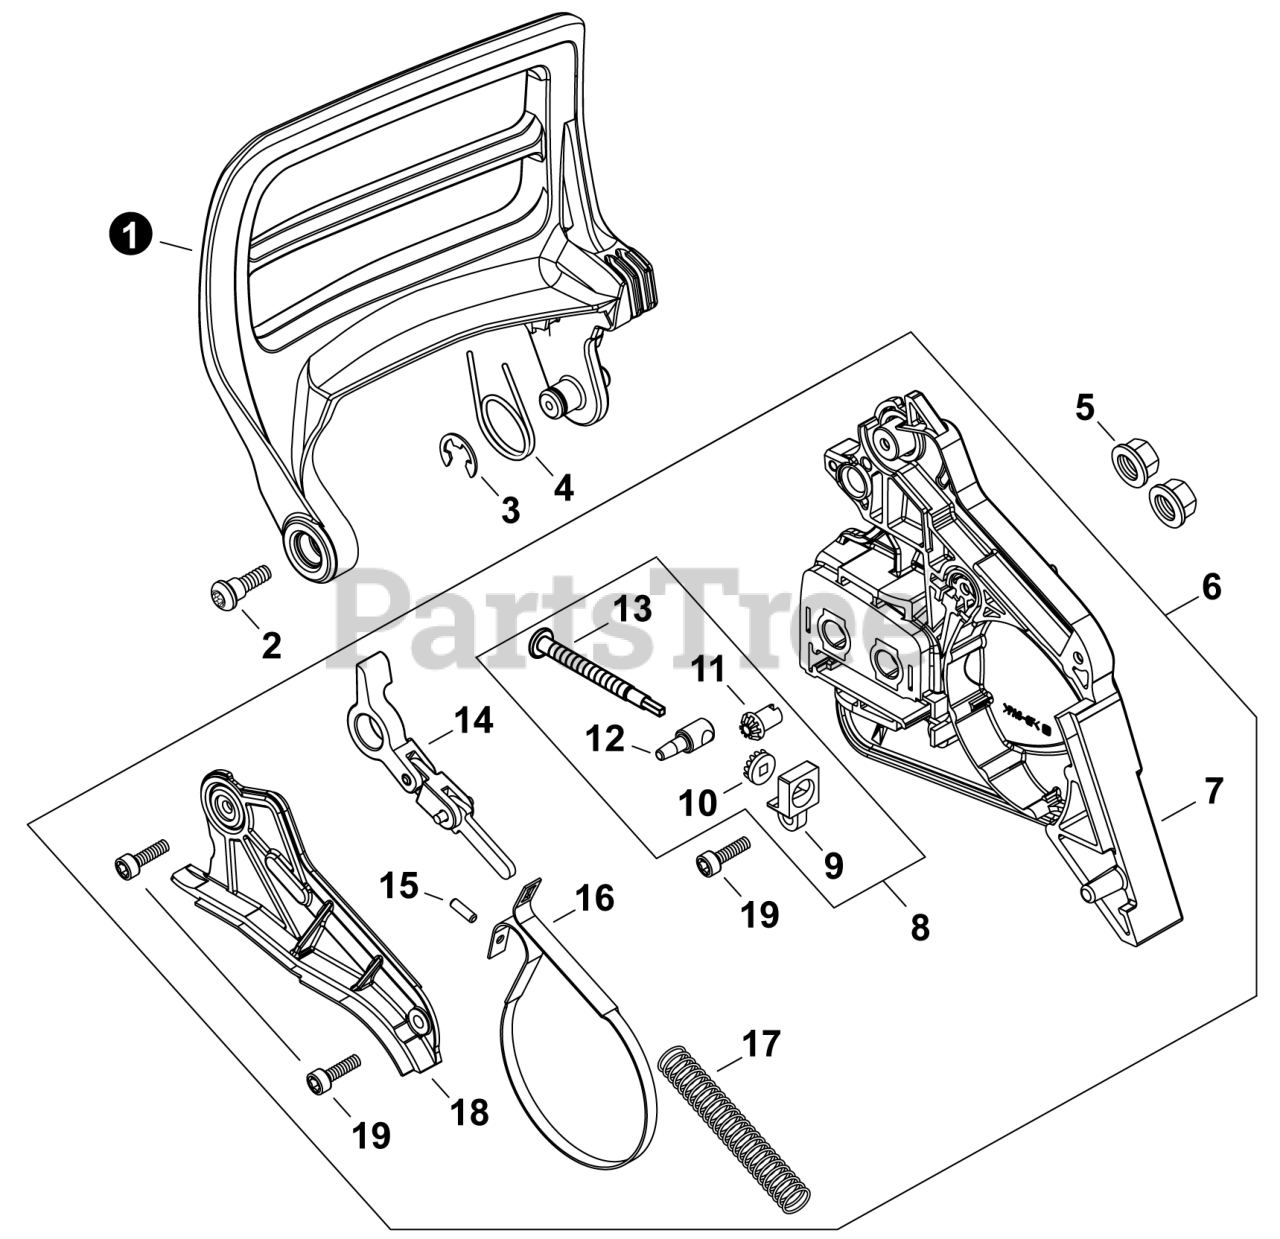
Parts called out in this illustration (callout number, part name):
1	LEVER, BRAKE
2	BOLT 5x13
3	RING, RETAINING - 8
4	SPRING, TORSION
5	NUT, FLANGE M8x1.25
6	SPROCKET GUARD ASSY
7	GUARD, SPROCKET
8	TENSIONER KIT, CHAIN
9	COLLAR 8
10	GEAR, BEVEL
11	GEAR, BEVEL
12	TENSIONER, CHAIN
13	SCREW, CHAIN TENSION
14	CONNECTOR, BRAKE
15	PIN, SPRING 3x9.8
16	BAND, BRAKE
17	SPRING, COMPRESSION
18	COVER, BRAKE
19	BOLT, TORX 4x12
